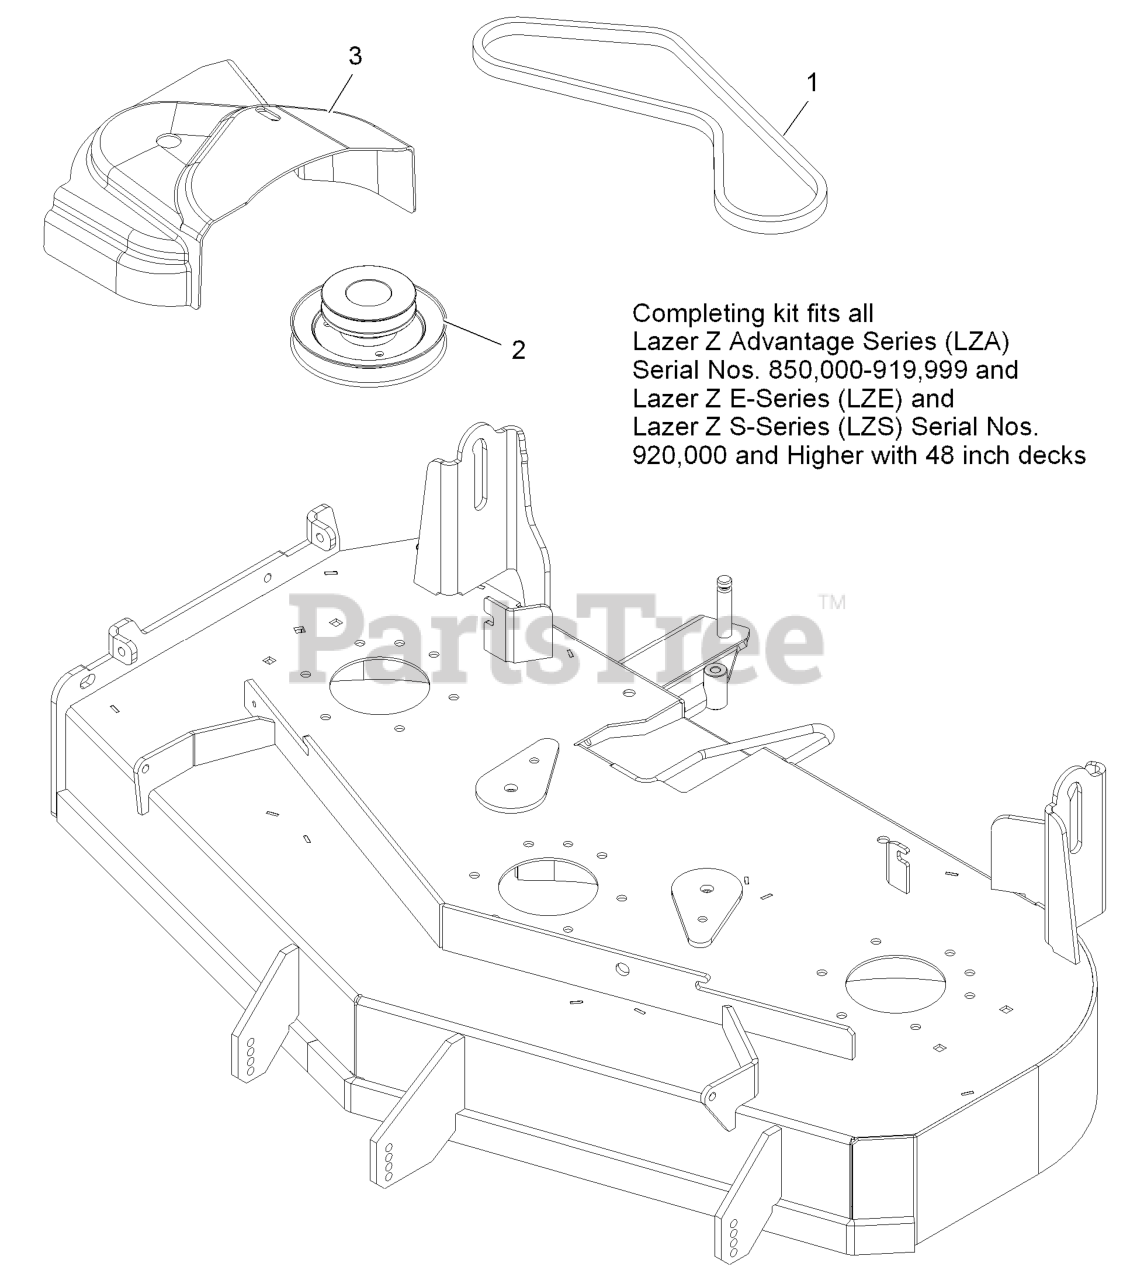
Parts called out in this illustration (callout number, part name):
1	BELT-BLOWER
2	JACKSHAFT-UV DRIVE, 484 S
3	COVER,BELT UV 48
